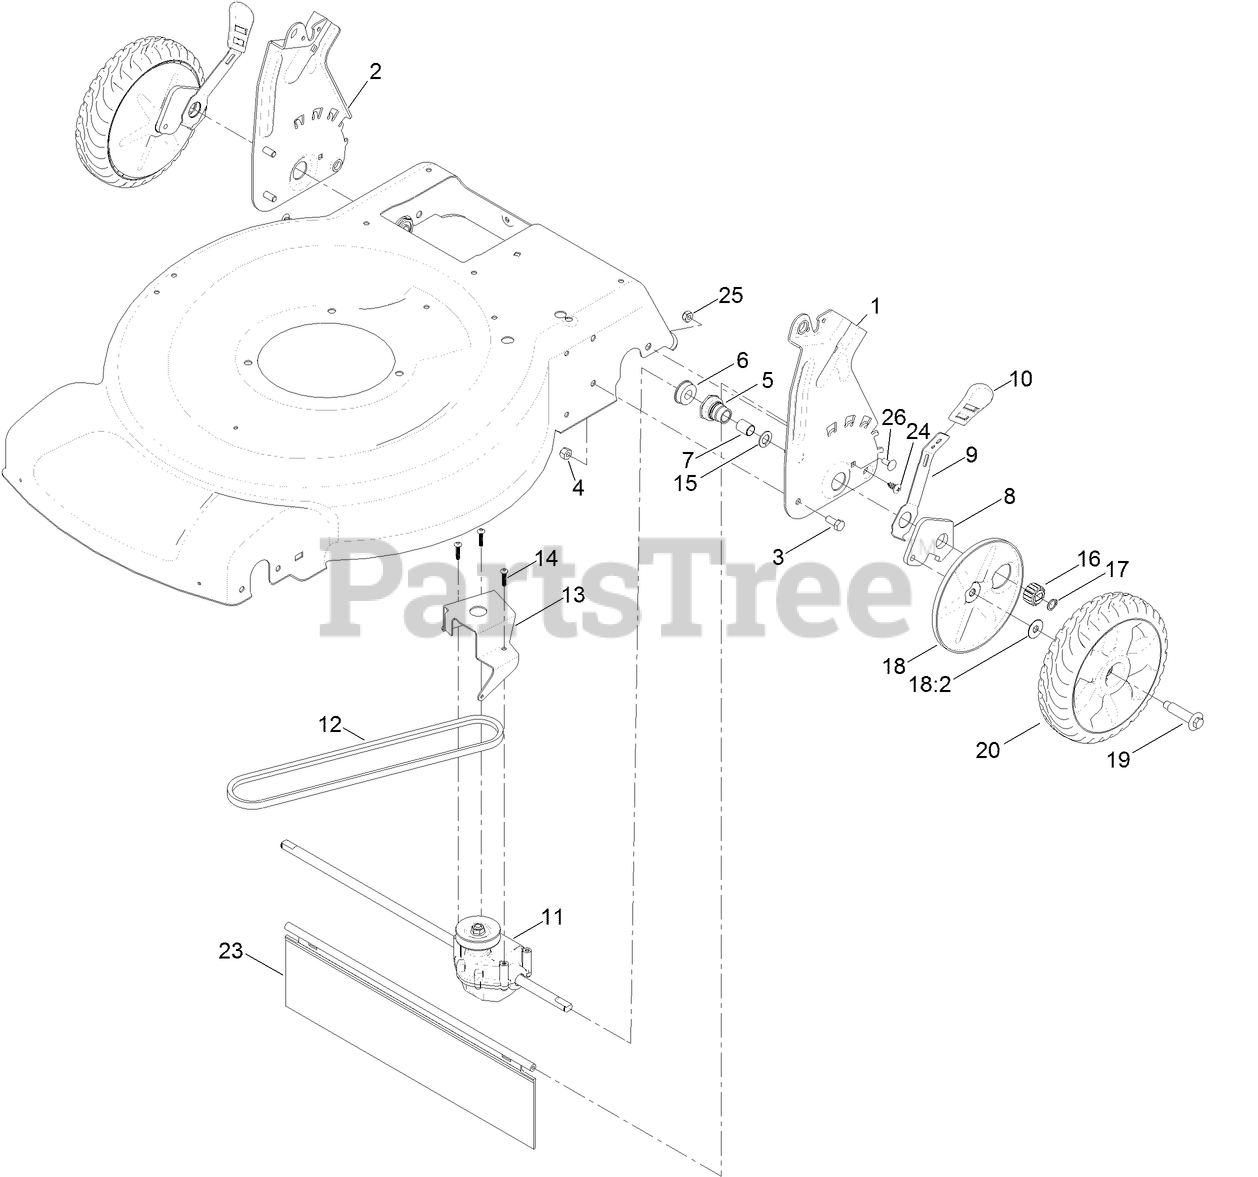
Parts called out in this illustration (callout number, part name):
1	PLATE-REAR, LH (HOC)
2	PLATE-REAR, RH (HOC)
3	SCREW-HH
4	NUT-LOCK, NI
5	RETAINER-BUSHING, HOC
6	BEARING-BALL
7	BUSHING-SLEEVE
8	ARM-PIVOT, REAR
9	ARM-SPRING
10	KNOB-HOC
11	TRANSMISSION ASM
12	BELT-V
13	BRACKET-TRANSMISSION
14	SCREW-PLASTITE
15	WASHER-THRUST
17	RING-RETAINING
18:2	WASHER-STEPPED
19	BOLT-SHOULDER
23	SHIELD-TRAILING
24	SCREW-PTH
25	SCREW-CARR
26	NUT-LOCK, NI
